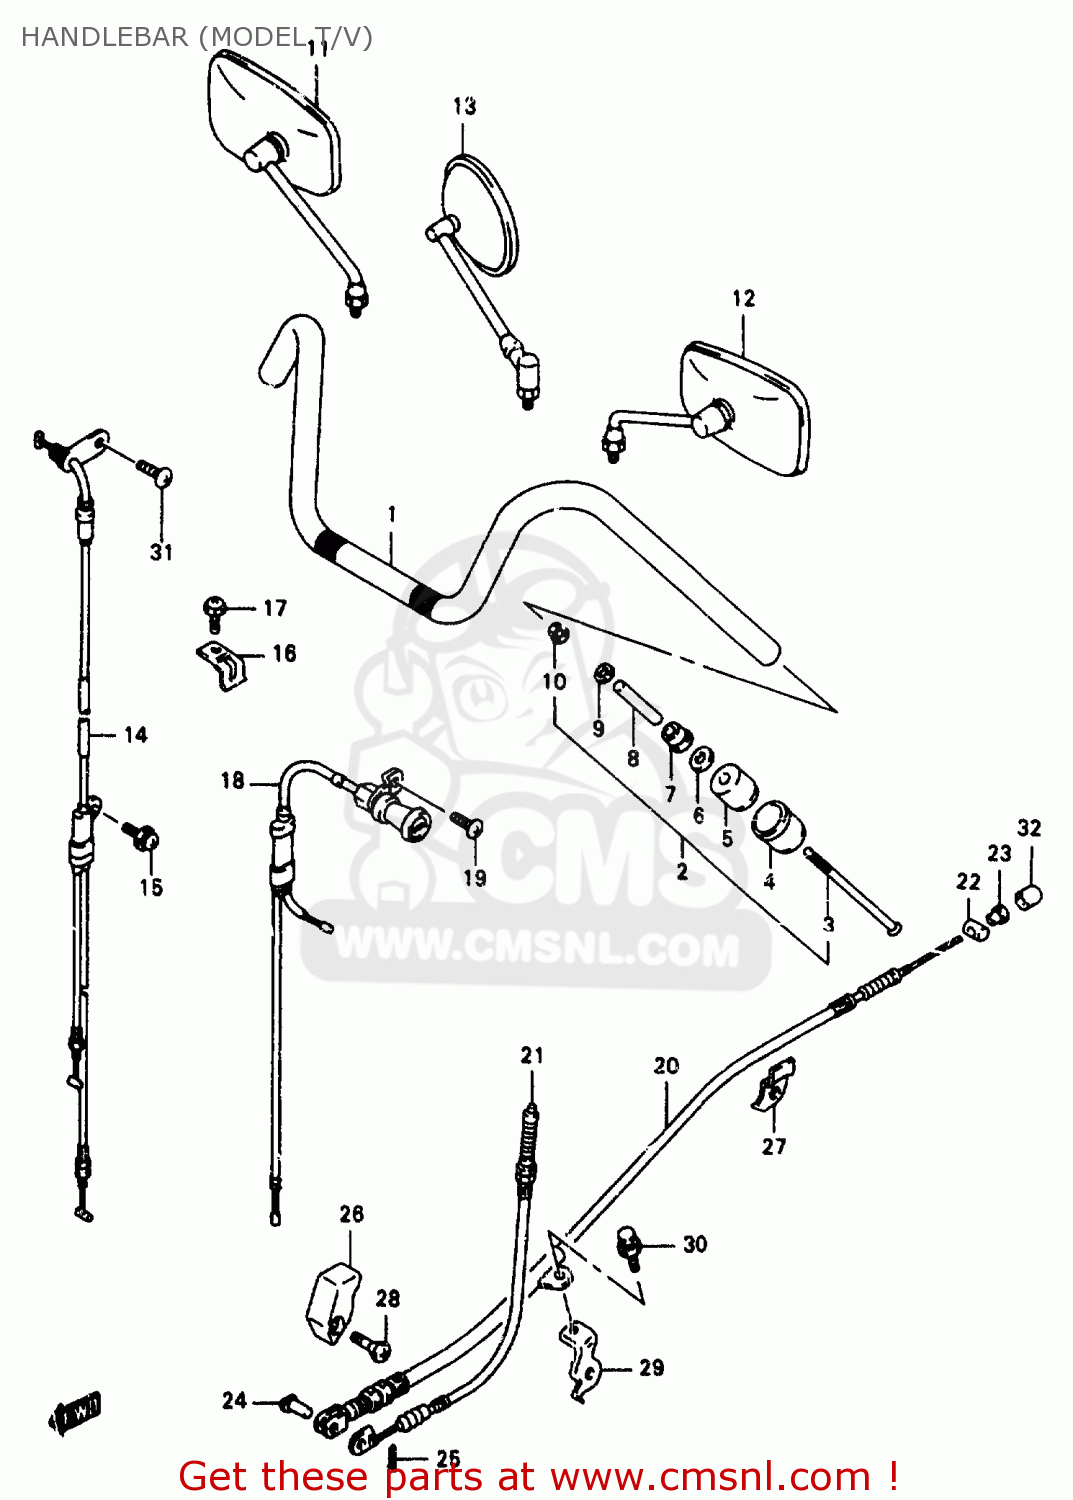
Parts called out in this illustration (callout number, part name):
1	HANDLEBAR
2	BALANCER SET,HANDLEBAR
3	SCREW(6X110)
4	CAP,HANDLE BALANCER
5	BALANCER,HANDLEBAR
6	SPACER,BALANCER
7	EXPANDER,HANDLE BALANCER NO.2
8	SPACER,EXPANDER
9	WASHER(6.5X18X1)
10	NUT
11	MIRROR ASSY,RR VIEW,R
12	MIRROR ASSY,RR VIEW,L
13	MIRROR ASSY,RH
14	CABLE ASSY,THROTTLE
15	SCREW
16	CLAMP,THROTTLE CABLE
17	SCREW
18	CABLE ASSEMBLY,STARTER
19	SCREW 6X10
20	CABLE,RR BRAKE
21	CABLE,STOP LAMP SWITCH
22	PIN
23	NUT
24	PIN(L:17.5)
25	PIN
26	GUIDE,RR BRAKE CABLE
27	CLAMP,RR BRAKE CABLE
28	SCREW
29	BRACKET,RR BRAKE CABLE
30	BOLT
31	SCREW
32	CAP,GREASE NIPPLE
